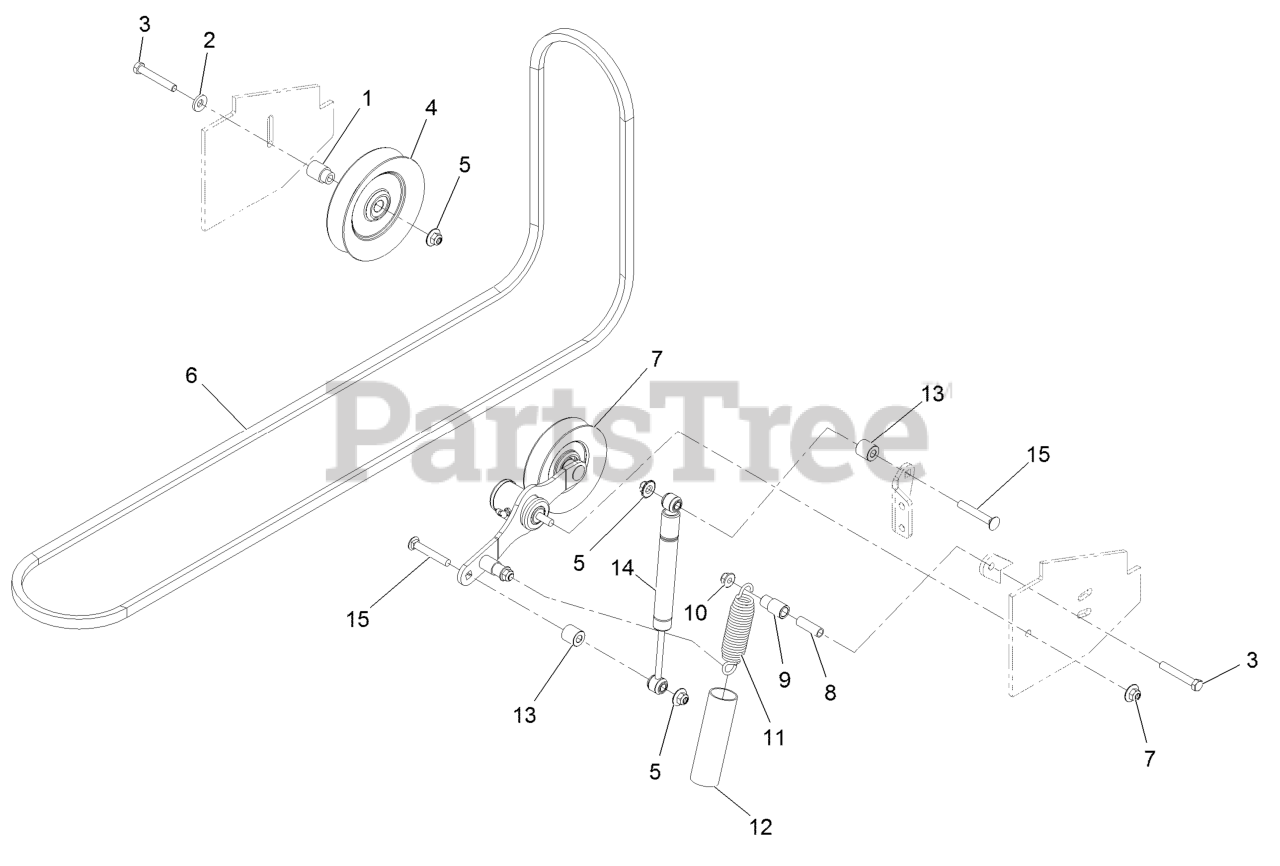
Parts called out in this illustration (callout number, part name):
1	BUSHING-IDLER
2	WASHER-BELLEVILLE
3	BOLT-CARR
4	PULLEY-IDLER
5	Nut-Nyloc 3/8-16 Flg
6	BELT,B 123.2
7	ASM-TTNR ARM W/PULLEY
9	BUSHING,PLASTIC
10	NUT-HF, NI
11	SPRING-EXTENSION
12	DAMPENER,SPRING
13	SPACER-.39IDX.88ODX.88L
14	DAMPER-MULE BELT DRIVE
15	SCREW-CARR
